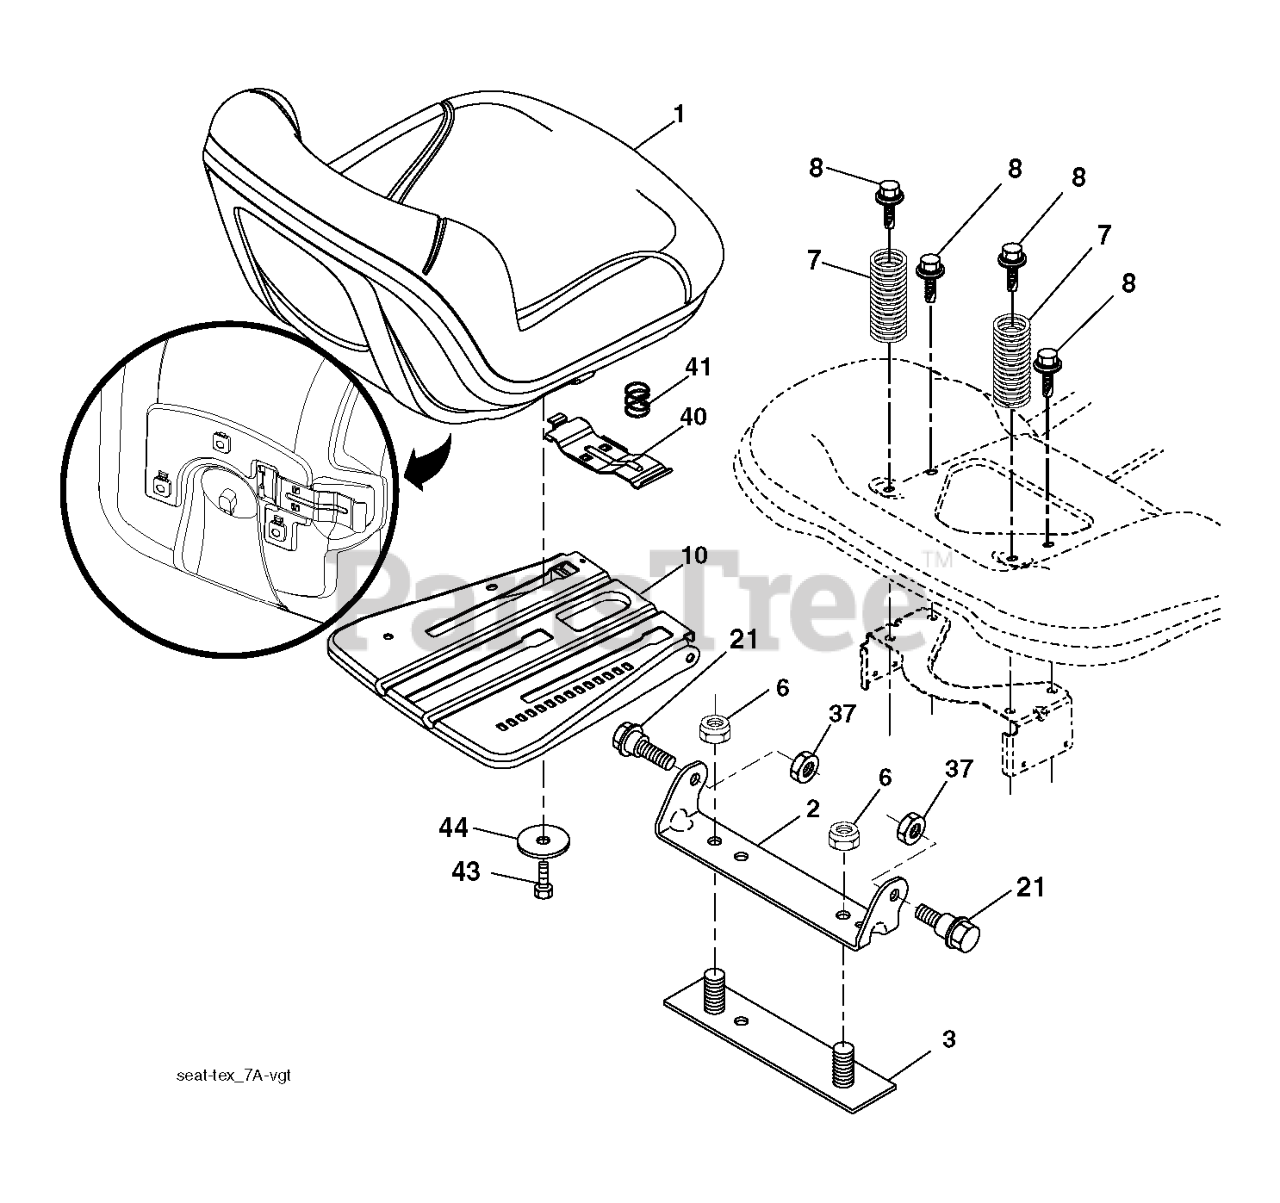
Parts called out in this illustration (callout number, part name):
1	RP SEAT, TH150, GREY, MILSCO
2	BRKT.PIVOT.FENDER
3	STRAP
6	NUT
7	SPRING COMPRESSION
8	BOLT.5/16-18UNCX3/4 W/SEMS.BLK
10	PAN.ASM.SEAT.3PT
21	BOLT.SHOULDER.5/16-18
37	NUT.71038.31-18.HEX.NYLOCK
40	HANDLE.SLIDE.SEAT.TEX.BLACK
41	SPRING.LATCH.SEAT.TEX
44	WASHER 13/32 X 2-3/8 X 12GA
